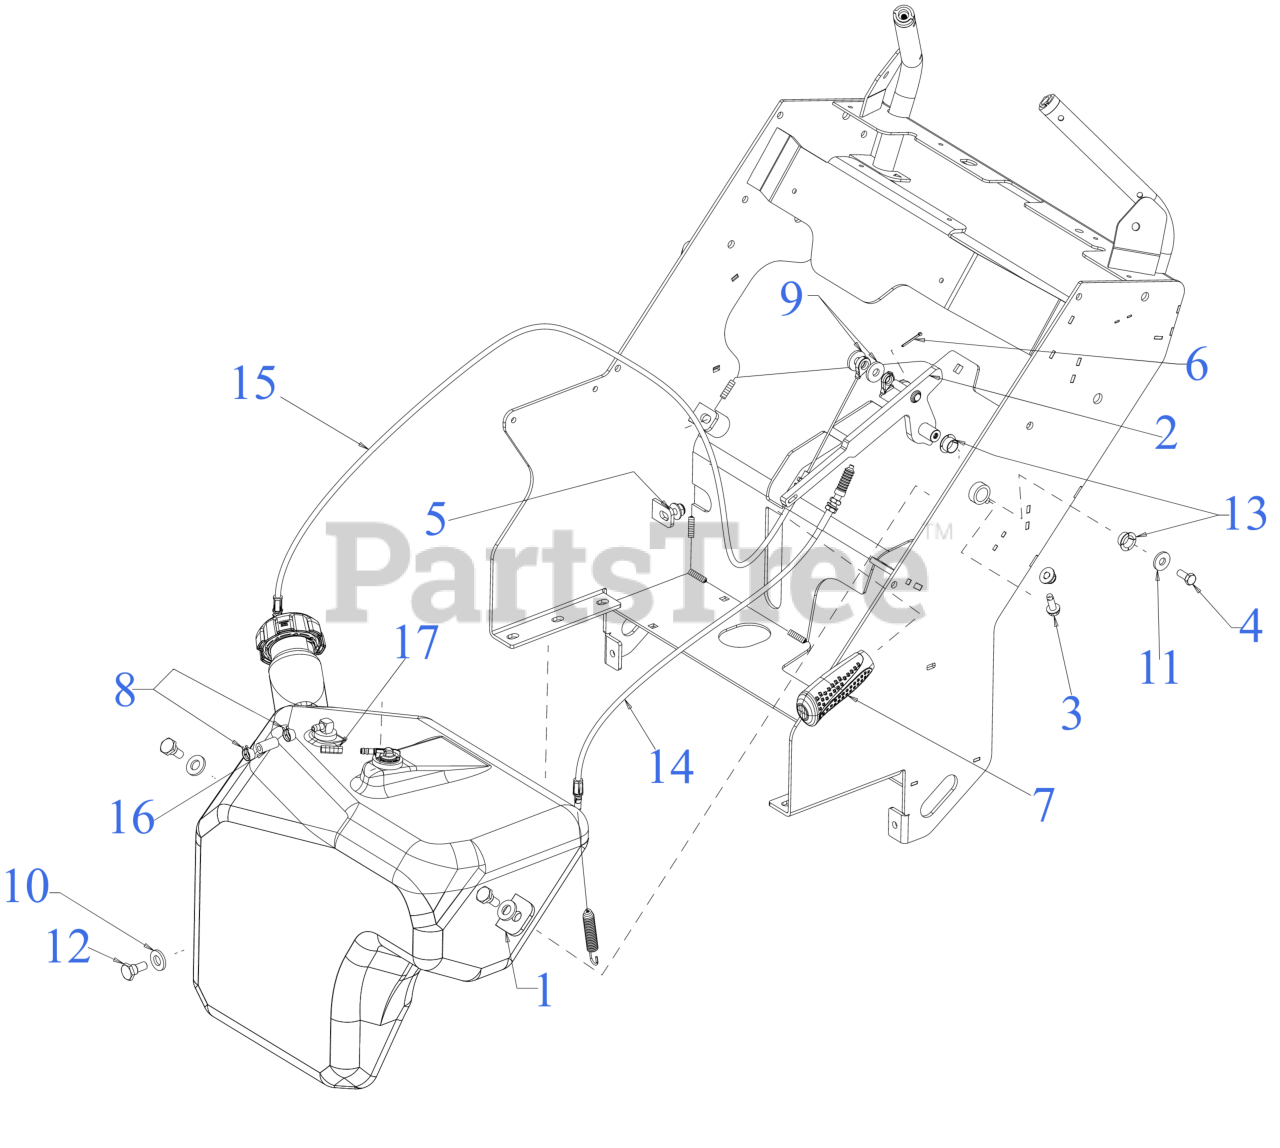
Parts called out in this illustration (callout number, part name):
1	FUEL TANK (5 GALLON)
2	BRAKE PIVOT WELDMENT
3	SCREW 5/16-18 x .875
4	SCREW 5/16-18 x .750
6	COTTER PIN-3/32
8	HOSE CLAMP 1/20
9	FLAT WASHER .385 x 1.00 x .135
10	FLAT WASHER .510 x 1.000 x .125
12	SHOULDER SCREW .498 DIA x .340
13	FLANGE BEARING .626X.938X.344
14	PARKING BRAKE CABLE (LH)
15	PARKING BRAKE CABLE (RH)
16	FUEL HOSE LOW PERMEATION 13"
17	VENT HOSE 3/16 ID 34"LG
